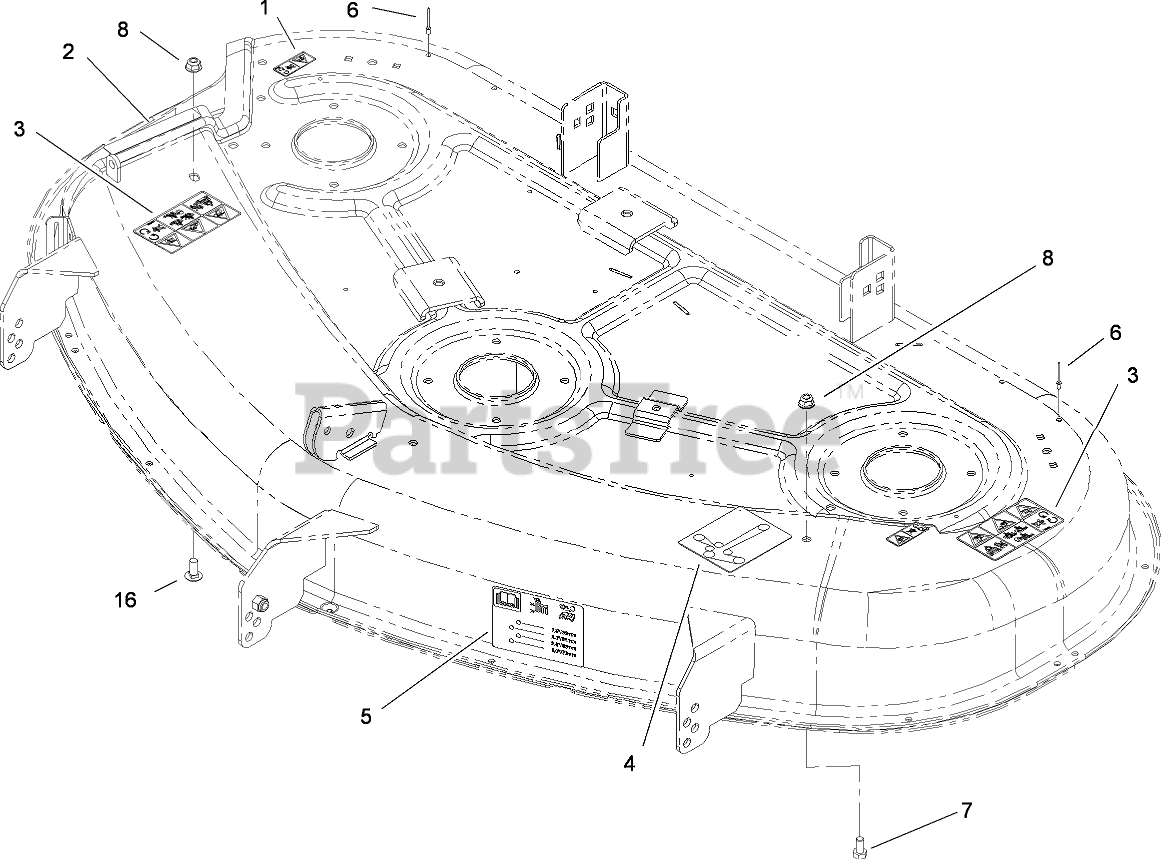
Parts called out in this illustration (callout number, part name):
1	DECAL-DANGER
2	DECAL-DANGER
3	DECAL-DANGER
4	DECAL-ROUTING, BELT
5	DECAL-SCALP, ANTI
6	RIVET-BLIND
7	SCREW-HH
8	NUT-HF, NI
16	SCREW-CARR
